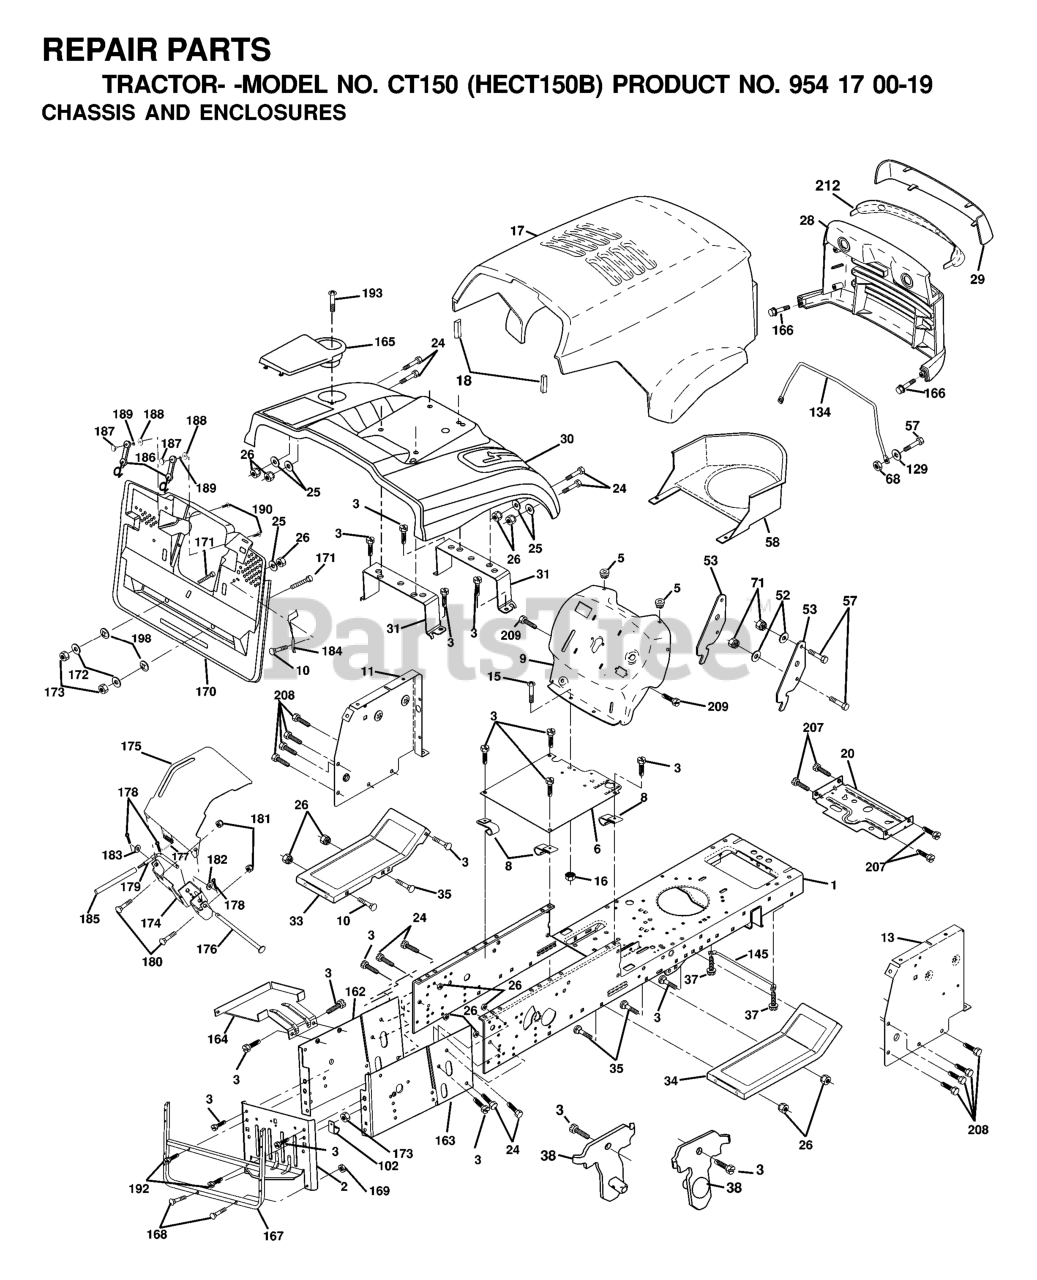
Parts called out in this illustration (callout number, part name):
1	CHASSIS STAMPING
3	SCREW 3/8-16X3/4
5	BUMPER.RUBBER.HOOD
6	SADDLE FLAT
8	CLIP,INSULATOR
10	BOLT D
11	PANEL DASH LH
13	PANEL DASH
15	Screw, Machine, Truss Head 5/16-18 UNC x 3/4
16	NUT
17	HOOD
18	BUMPER HOOD T
20	PLATE MTG
25	WASHER
26	NUT
28	GRILL
29	LENS
31	BRACKET SUPPORT FENDER
33	FOOT REST LH
34	FOOTREST RH
37	Screw 5/16-18 x 1/2 Hex, Self Tapping 5/16-18 x 1/2
38	BRACKET
53	BRACKET PNT PICK OFF LT/PL
57	BOLT
58	AIR DUCT P/L/LT
68	NUT
71	NUT.CROWNLOCK.1/4
102	CLIP T
134	ROD SUPPORT HOOD LT/PL HUS.
145	ROD PIVOT CHASSIS/HOOD
165	COVER BATTERY
166	SCREW
167	SUPPORT.ASM.BACKPLATE
168	BOLT.ROUND.HEAD.SQUARE.NECK
169	NUT T
170	COVER BACKPLATE
172	WASHER
176	HINGE PIN
177	SPRING COVER LH
178	COTTER PIN
180	BOLT RB
181	LOCKNUT
183	WASHER
185	TUBE LEVER
186	LATCH ASSY
187	WELDNUT
189	LOCKWASHER #10
190	SCREW
192	SCREW LT
193	Screw Truss 1/4-20 x 3/4 Tap/R
194	SCREW 3/8-16X3/4
207	SCREW, 5/16-18 X 1/2
208	SCREW 3/8-16X1/2
209	SCREW, 3/8-16X3/4
212	INSERT LENS REFLECTOR
